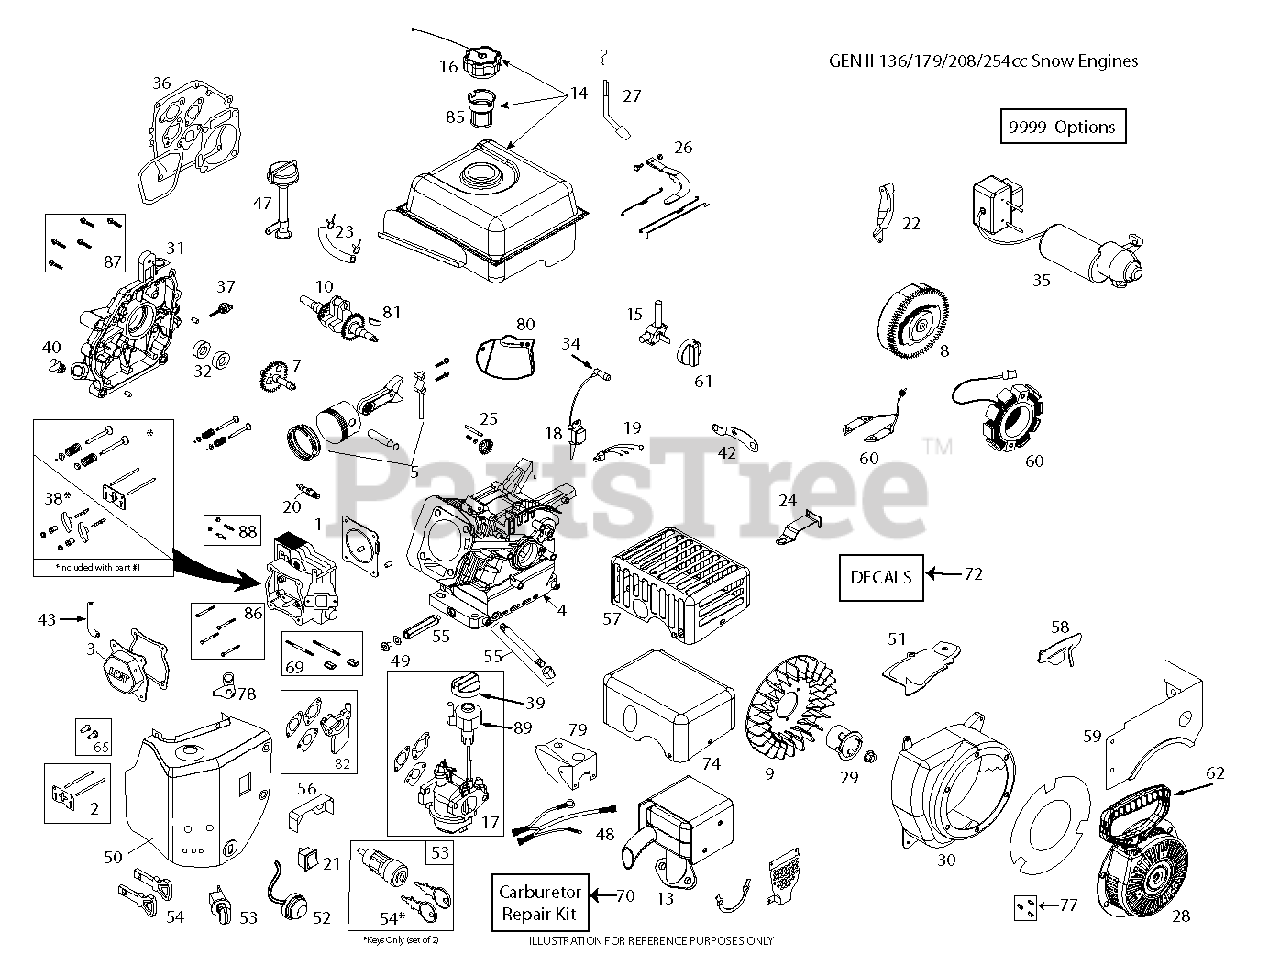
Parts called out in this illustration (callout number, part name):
1	CYLINDER.HEAD.ASM.W/GASKET.254
2	KIT.PUSH.ROD.&.PLATE.W/VC.GASK
3	COVER.VALVE.W/GASKET.254CC
4	CYLINDER LCT 254 FT OIL DRAIN
5	PISTON.&.ROD ASSEM.254CC
7	CAMSHAFT.MCR.W/GASKET.254CC
8	FLYWHEEL.ELEC.STRT.(8.MAGNETS)
9	KIT.COOLNG.FAN.SERV(SK208-4000
10	CRANKSHAFT KEYED #18 LCT 254
13	MUFFLER.ASSEM.GEN2.SNOW.254CC
14	FUEL TANK LCT 254 2.7L GLOSS
15	FUEL.PETCOCK.SNOW(SKSN4900)
16	FUEL CAP OVERSIZED CLICK STYLE
17	CARBURETTOR LCT 254 W/IDLEDOWN
18	COIL.ING.CDI.HI TEMP.SKSNO416.
20	PLUG.SPARK.PLAT.SKSN2404.1
21	SWITCH.ON/OFF(SKSN-0403)
22	SHIELD.FLYWHEEL.ELEC.STRT.208C
23	FUEL HOSE KIT
24	BRACKET.SPEED.CNTRL.FIXED.254C
25	GOVENOR.GEARS ASM(SK2082900)
26	KIT.GOVERNOR.ARM.&.LINK.254CC
27	KIT.GOVERNOR.CRANK(SK208-3100)
28	RECOIL.STRT.ROUND(BLK) SNOW
29	STRTER.CUP(NON-SLOT)SKSN0601.2
30	BLOWER HSG.LCT 254 GLOSS BLK S
31	CRANKCASE.CVR.PRESS.IN.HI-OIL.
32	KIT.SEAL.OIL.2.PIECES.254CC
34	SPARK.PLUG.BOOT.SNW,SKSN4691.1
35	STARTER.EL.230C.SNO.LCT.208CC.
36	KIT.ENGINE.GASKET.254CC
38	KIT.ROCKER.ARM.W/GASKET.254CC
39	CHOKE.KNOW.SNOW(SKSN4500)
40	NON REMOVABLE PLUG
43	TUBE.BREATHER.LCT.208
47	TUBE ASSY HIGH OIL-FILL
48	WIRE.HARNESS.SNOW
49	KIT.OIL.DRAIN.PLUG(SK2089911
50	BOX HEATER ASM.LCT 254
52	PRIMER.BULB.WITH HOSE (SNOW)
53	SWITH.KEY.ASSEM.SNOW.SINGLE.ST
54	KEY SET(2 KEYS) SKSN0407.1
55	OIL PIPE DRAIN LCT 254
56	SHIELD.CARBURETOR.VAPOR
57	SHIELD.MUFFLER.CE.COMPLIANT
58	SHIELD.GOVERNOR.LINKAGE.254CC
59	FUEL TANK SKIRT SHIELD LCT 254
60	208CC 60W ALTERNATOR
61	FUEL KNOB-SNOW
62	HANDLE.RECOIL.DELUXE.LCT
65	TAPPET.KIT.LCT.208CC
69	CARB.STUDS & COUPLING KIT.SNOW
70	CARB.REPAIR.KIT.LCT.SK9900.2
74	COVER.MUFFLER.HEAT.SHIELD.
77	BOLT.KIT.RECOIL.LCT.ALL.ENGINE
79	COVER.CARBURETOR.SNOW
80	SHIELD.GOVERNOR.LINK.SNOW.254C
81	KEYS.FLYWHEEL.208/414CC.5PACK
82	SPACER.CARBURETOR.208CC.LCT
85	DECAL.HOOD.RH.
86	KIT.BOLT.CYLINDER.HEAD.(4PC)
87	KIT.BOLT.CRANKCASE.COVER.6PC
88	STUD.MUFFLER.KIT.LCT
89	KNOB LCT.SKSN5325.1 SPEED
9999	JET HIGH ALTITUDE LCT 5000 25
